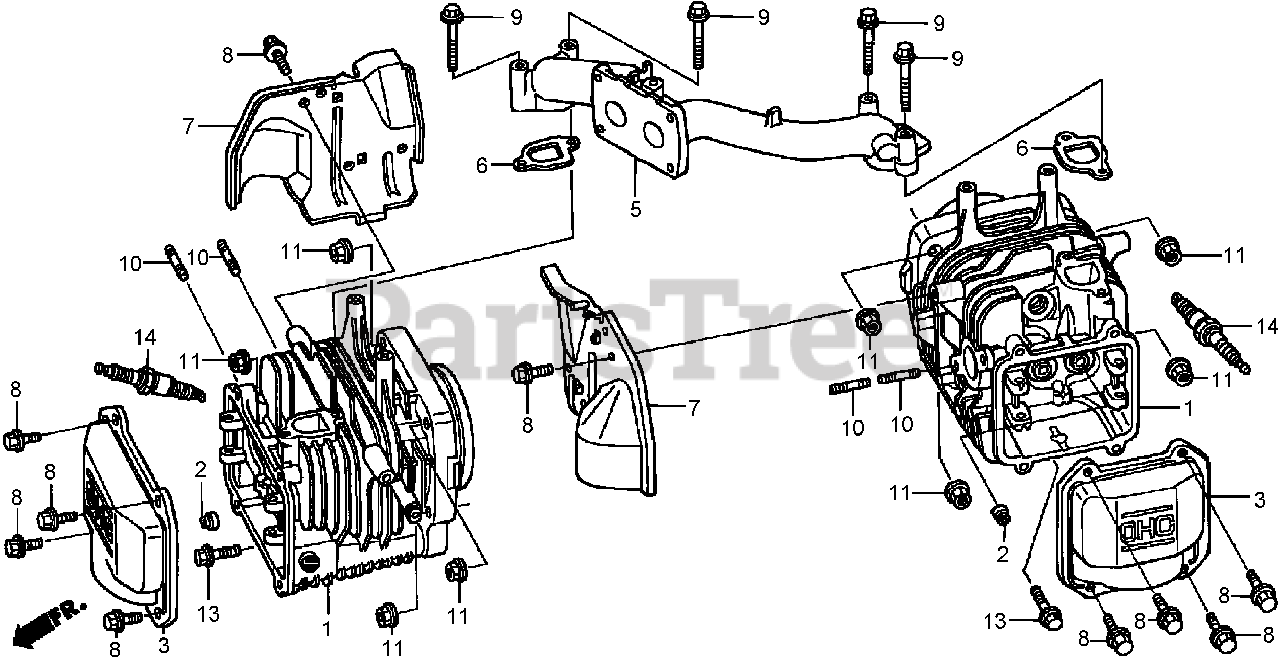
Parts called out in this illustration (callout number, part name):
1	CYLINDER
2	SEAL-STEM, VALVE
3	COVER-HEAD
5	MANIFOLD-INTAKE
6	GASKET-MANIFOLD, INTAKE
7	SHROUD
8	BOLT-FLANGE (6X12) (C T200)
9	BOLT-FLANGE (6X45) (C T200)
10	BOLT-STUD (6X28)
11	NUT-FLANGE (8MM)
13	BOLT-FLANGE (6X30)
14	SPARK PLUG (B P R4E S) (N G K)
14	SPARK PLUG (W14E P R-U) (DENSO)
14	SPARK PLUG (B P R 5E S) (N G K)
14	SPARK PLUG (W16E P R-U) (DENSO)
